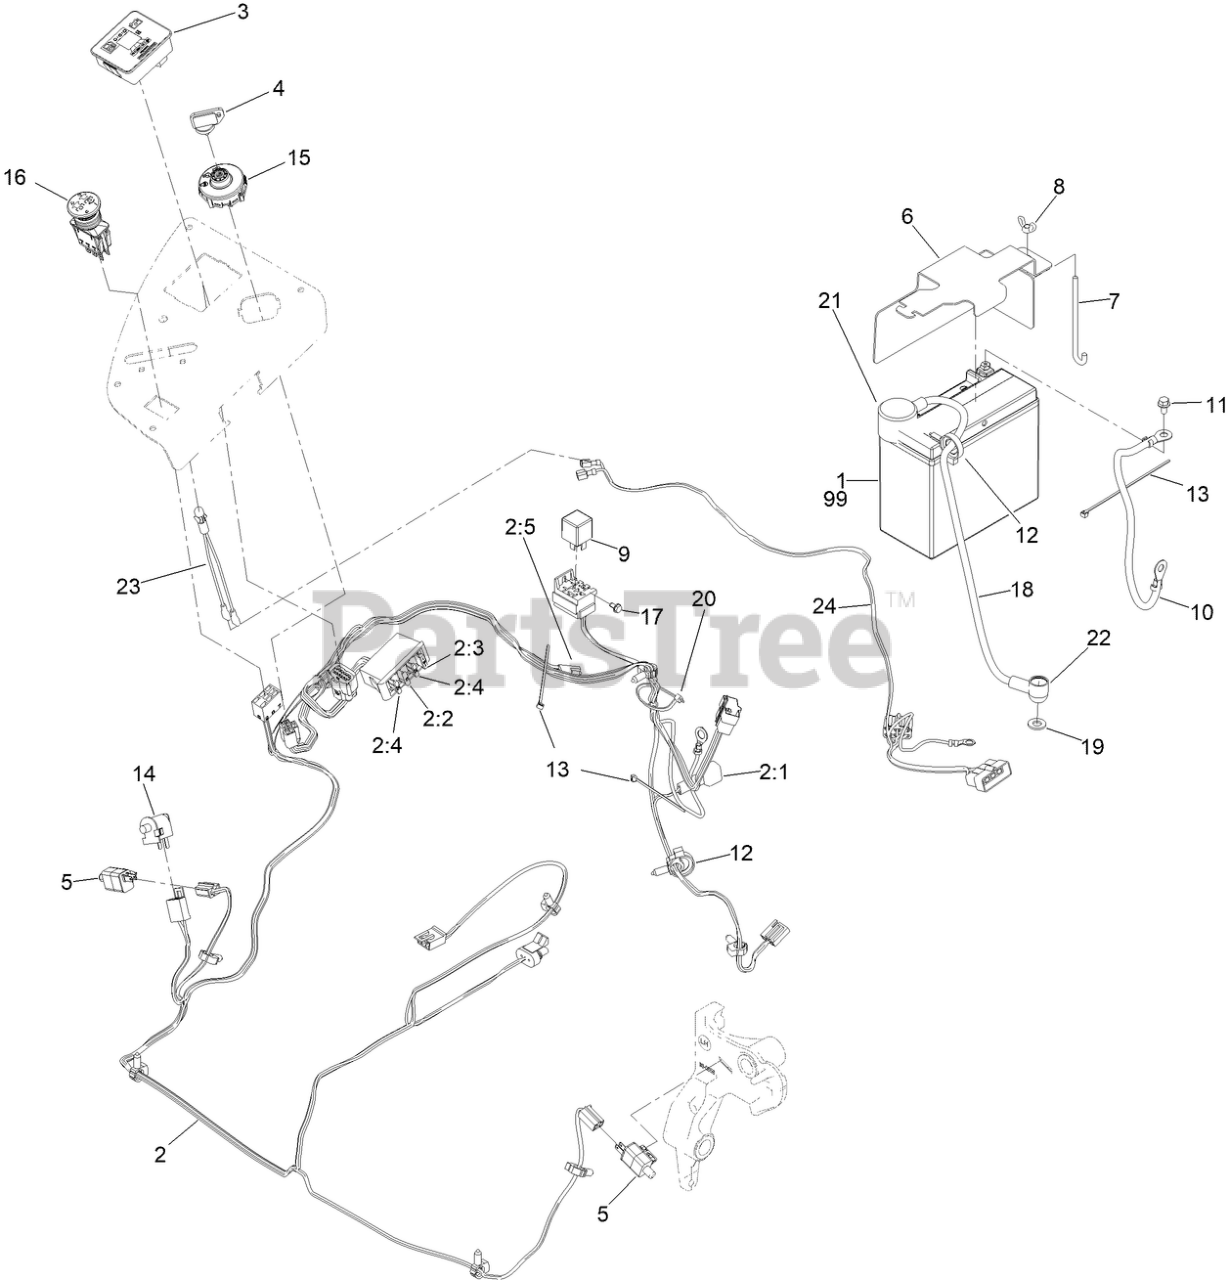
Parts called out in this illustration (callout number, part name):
1	BATTERY-AGM
2	HARNESS-WIRE, MAIN
2:2	FUSE-BLADE, 10 AMP
2:3	FUSE-BLADE, 15 AMP
2:4	FUSE-BLADE, 25 AMP
2:5	CAP-PLUG
3	FUEL/HOUR METER ASM
4	KEYS-IGNITION (SPARE PAIR)
4	KEY-IGNITION
5	SWITCH
6	BRACKET-HOLDDOWN, BATTERY
7	BOLT-HOLDDOWN
8	WINGNUT
10	CABLE-BATTERY, BLACK
11	SCREW-HHF
12	CLAMP-HOSE
13	TIE-CABLE
14	SWITCH-BAIL
15	SWITCH-IGNITION
16	SWITCH, PTO 10A
17	SCREW-HWH
18	CABLE-BATTERY, POSITIVE
19	WASHER-FLAT
20	TIE-CABLE
21	INSULATOR-BATTERY
22	INSULATOR-SOLENOID
23	INDICATOR-LED, RED
24	HARNESS-INDICATOR LIGHT
99	HARDWARE KIT, BATTERY
